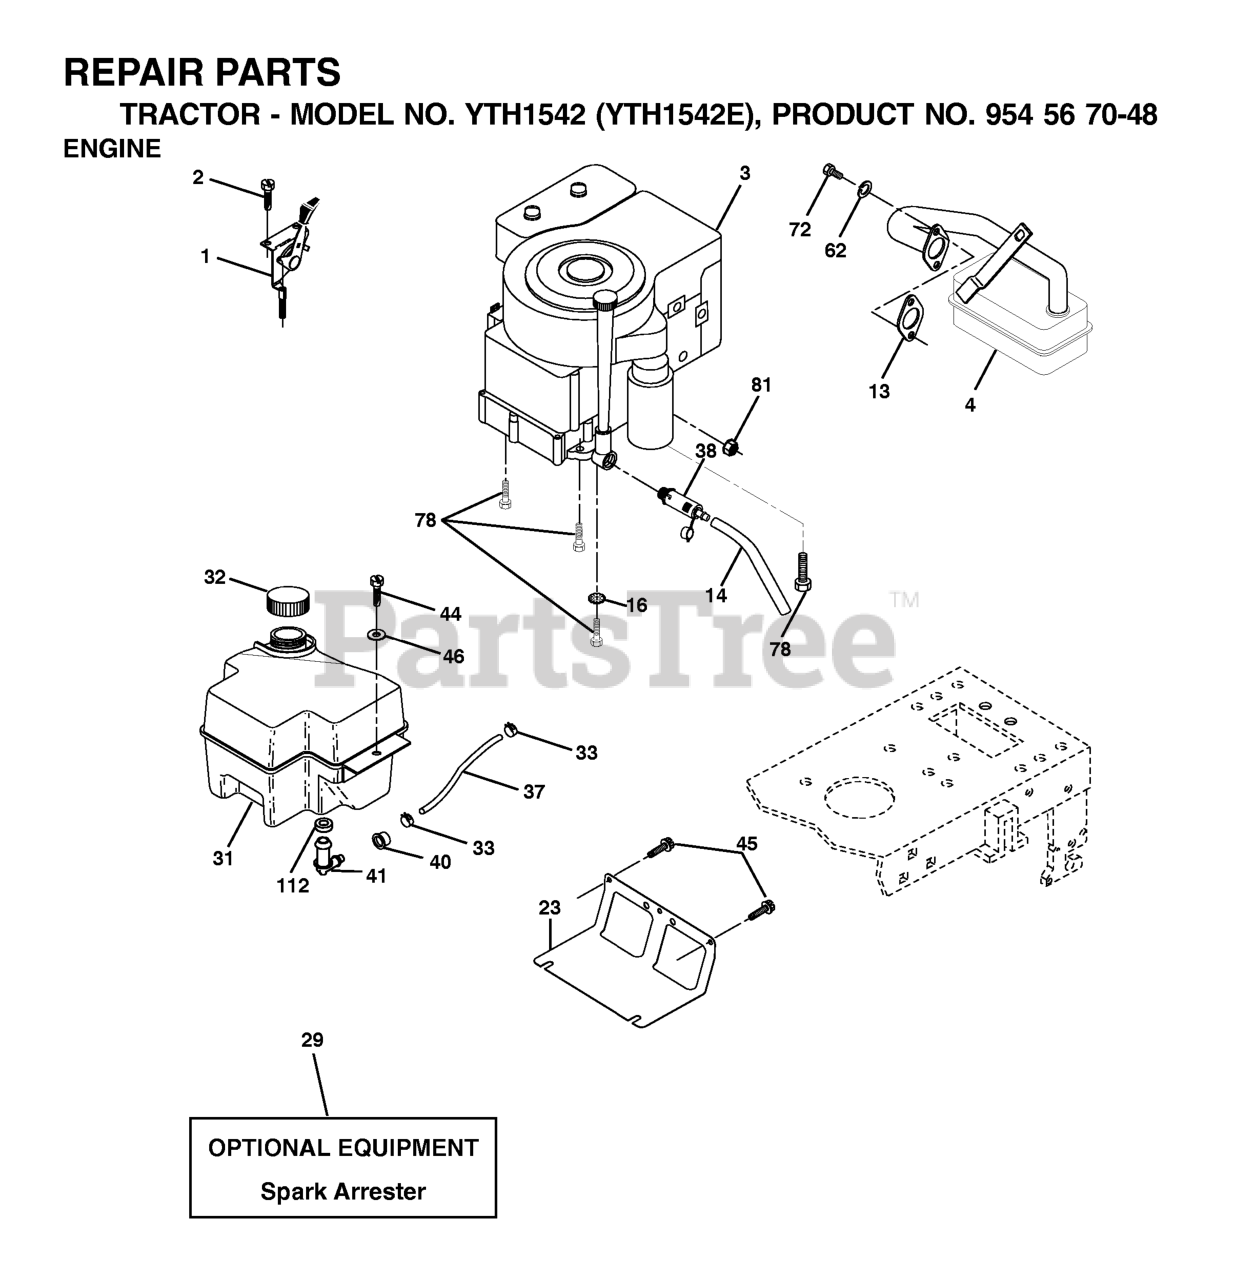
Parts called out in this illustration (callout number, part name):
1	CONTROL.THROTTLE/CHOKE.BLACK
2	SCREW
4	MUFFLER.LT.BRIGGS.14HP.IC/OHV
13	REPL BY 532 27 22-93
14	TUBE, DRAIN OIL ASM.
16	LOCKWASHER
23	SHIELD.BROWNING.DBR.GUARD
29	KIT.SPARK ARRESTOR 794945 B&S
31	GAS TANK 2GAL
32	FUEL CAP
33	HOSE CLAMP
37	LINE.FUEL.20
38	PLUG, OIL DRAIN EASY
40	BUSHING.SNAP.NYL.BLK.
41	STEM FUEL TANK
44	SCREW HEXWSHR 1/4-20X3/4
45	SCREW, 3/8-16X3/4
62	WASHER.LOCK.HVY.HLCL.SPR.5/16
72	SCREW
78	SCREW.3/8-16
81	NUT
112	BUSHING OUTLET T
